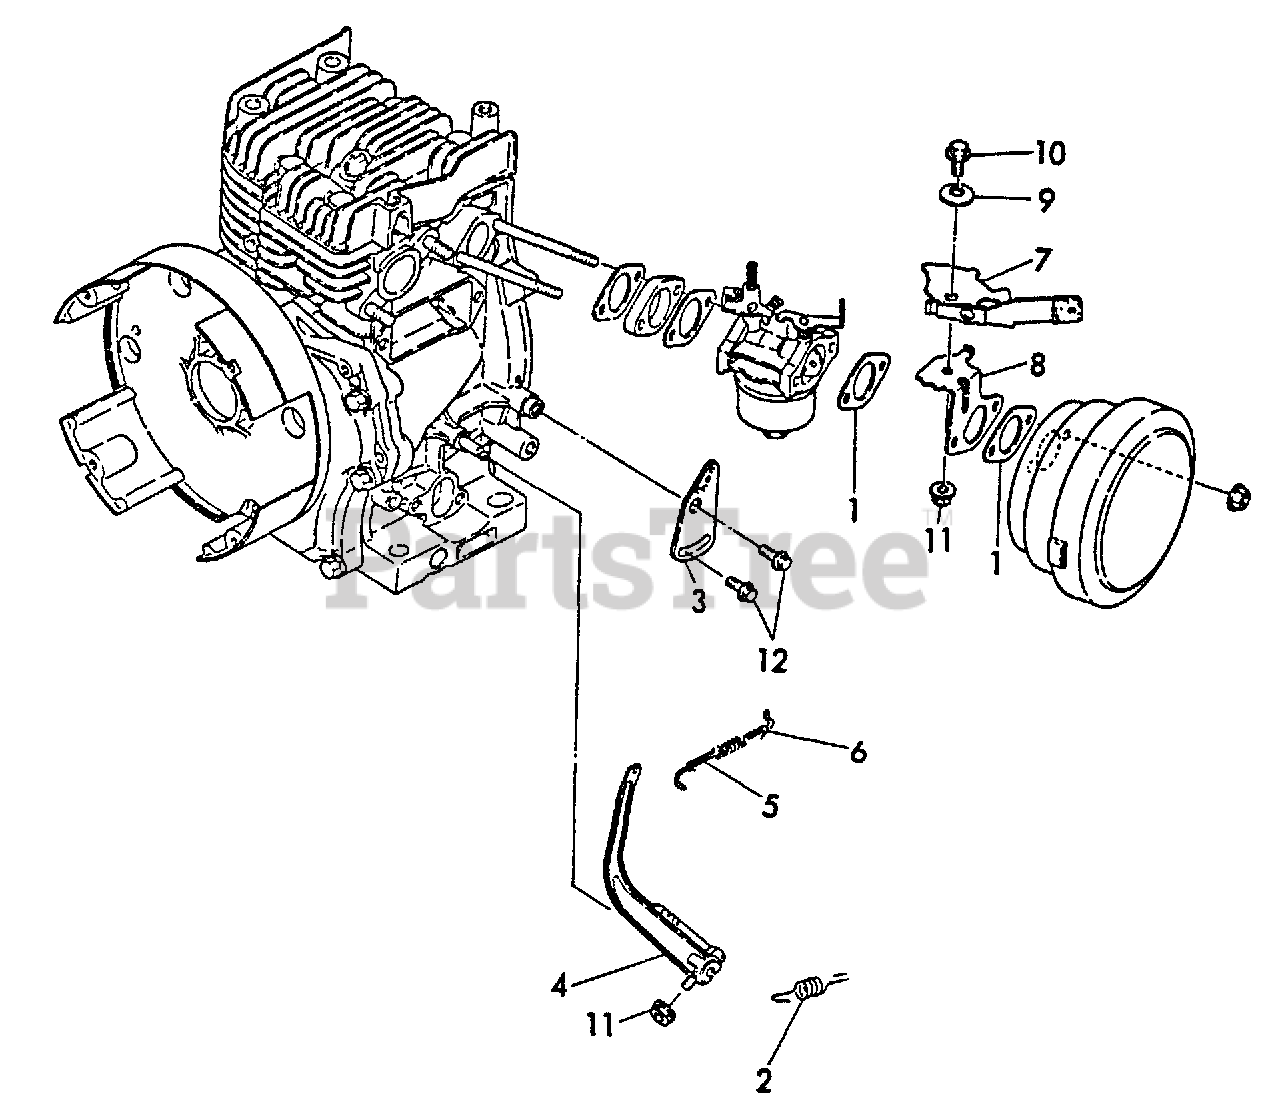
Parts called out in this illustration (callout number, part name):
1	GASKET, INTAKE
2	SPRING, REGULATOR
3	HANDLE, REGULATOR
4	LEVER, GOVERNOR
5	LINK, THROTTLE
6	SPRING
7	LEVEL ASSY
8	BRACKET
9	COLLAR
10	BOLT - 6X12 -- PLATED
11	NUT - 6 -- FLANGE
12	BOLT - 6X8 -- PLATED
